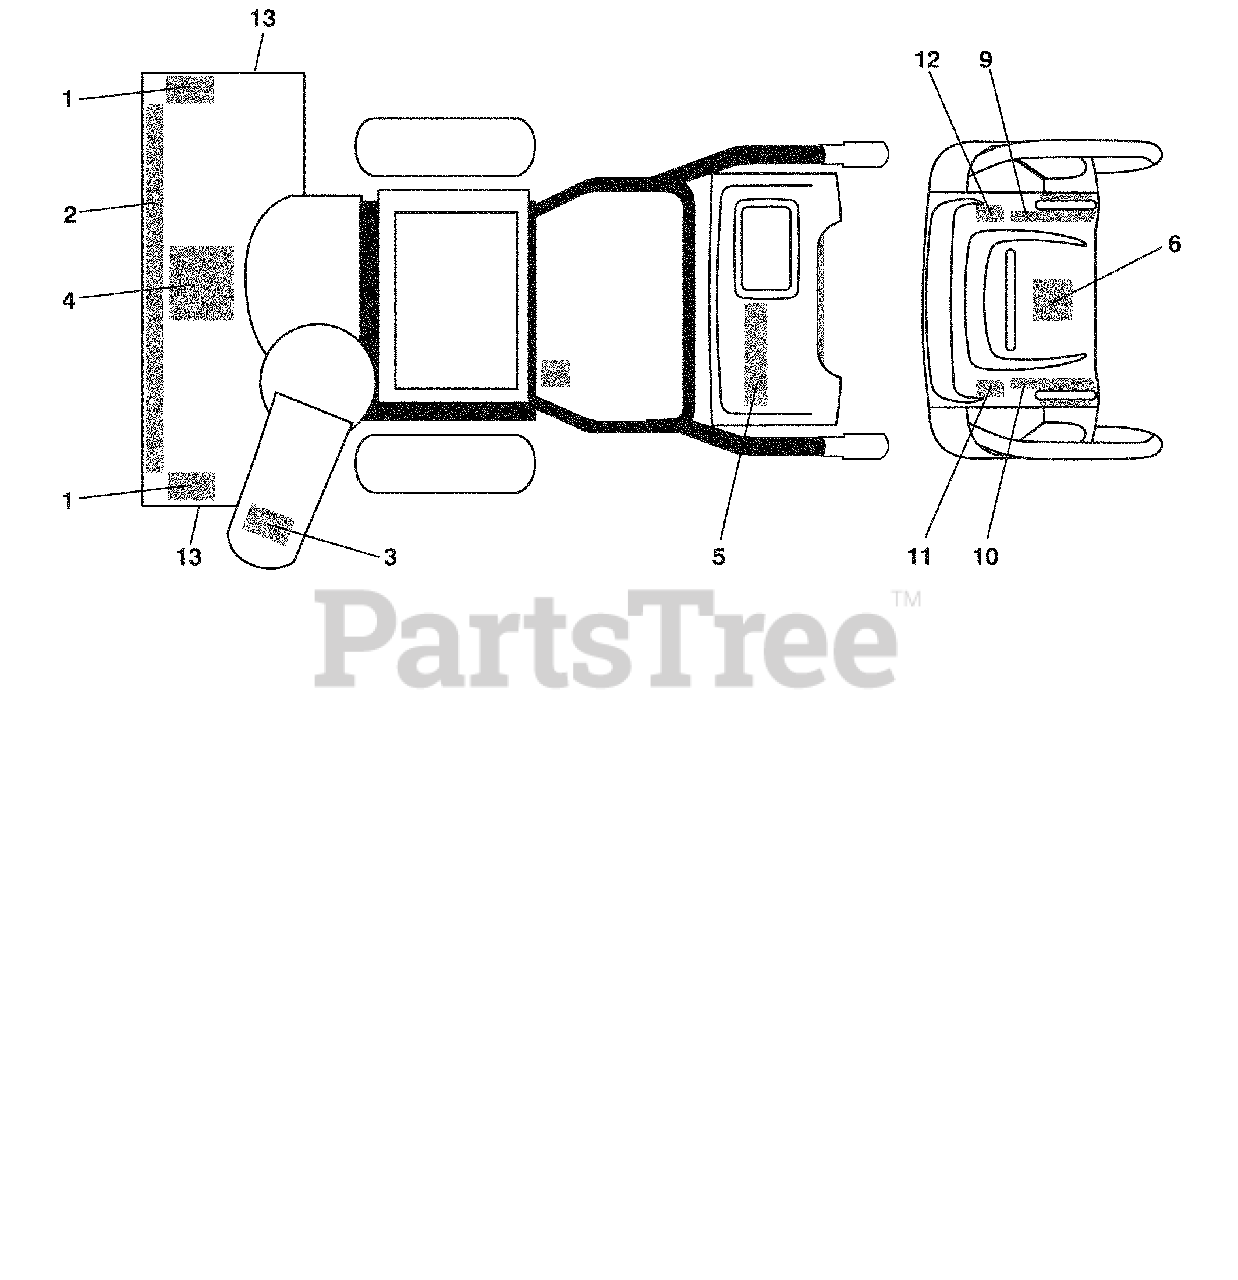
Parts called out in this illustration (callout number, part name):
1	Decal, Danger
2	Decal, Husqvarna
3	Decal, Danger, Deflector
4	Decal, Danger
5	Decal, Husqvarna, 1130SBE
6	Decal, Instruction
9	Decal, Speed Control
10	Decal, Remote Deflector
11	Decal, LH Trigger
12	Decal, RH Trigger
13	Decal, Husqvarna, Crown
